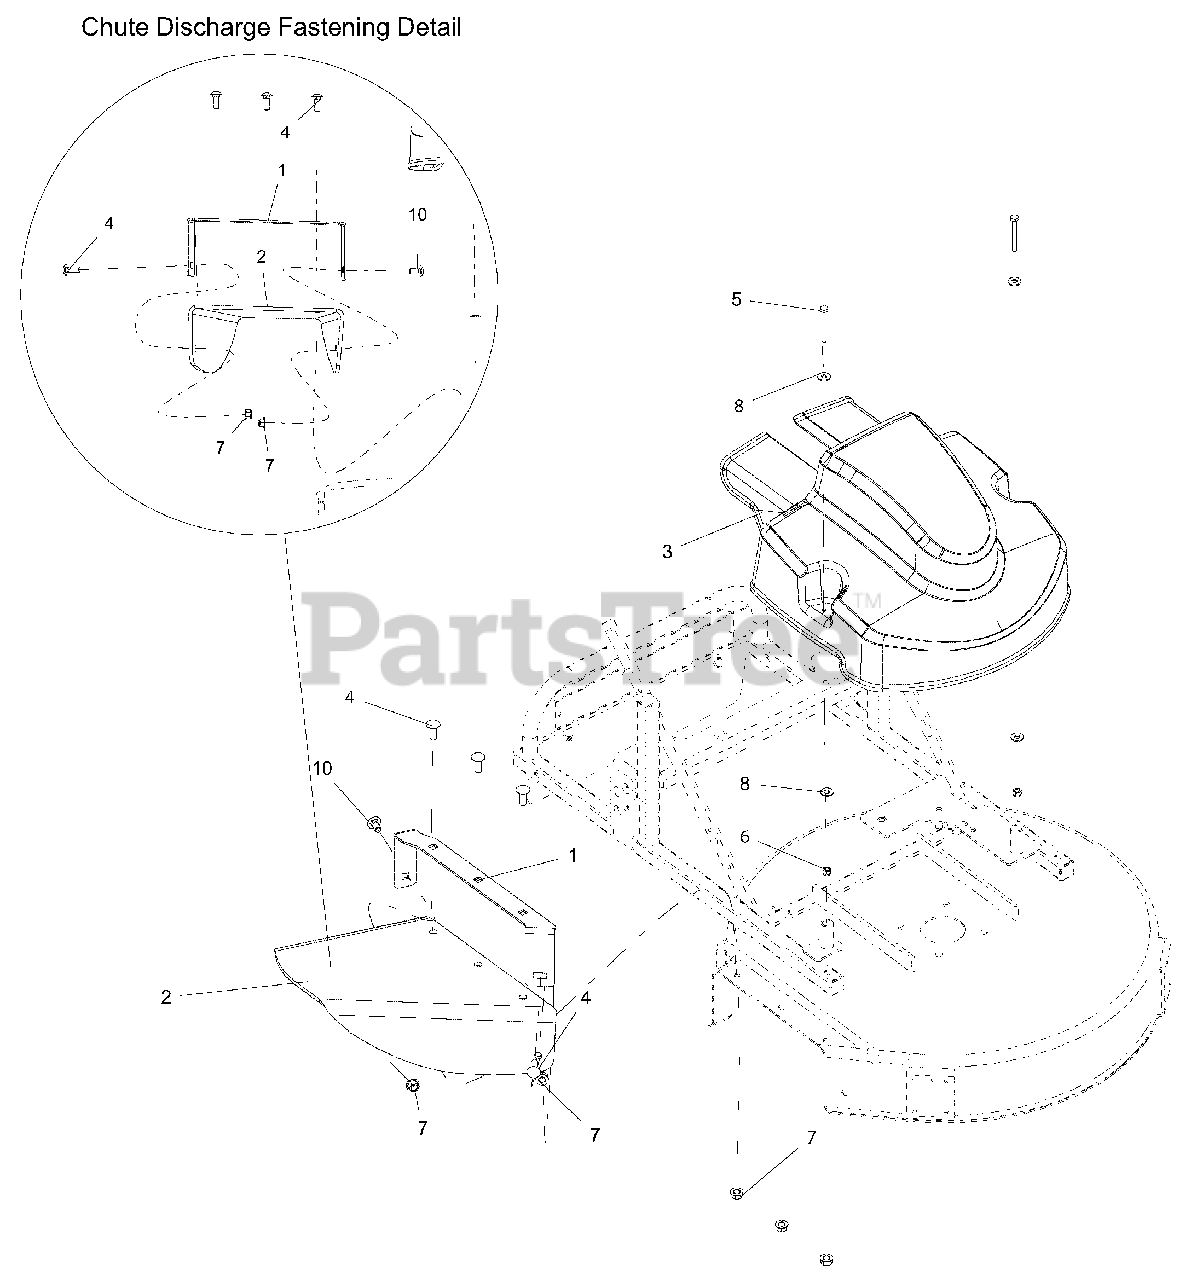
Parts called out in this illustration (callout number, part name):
1	BRKT, DISCHARGE CHUTE, HWM (BLACK)
2	CHUTE, RUBBER DISCHARGE
3	COVER, PLASTIC BELT-HIGH WHEEL
4	BLT-RDHDSQNK .38-16X1.00 G5 YWZC
5	BLT-HEX .25-20X2.25 GR5 YWZC
6	NUT-LK-NYL .250-20 YWZC
7	NUT, LK-TOP-FLG .38-16 YWZC
8	WSHR-FL-STL.312X.734X.065 YWZ
10	BLT-RDHDSQNK .38-16X.75 G5 YWZC
